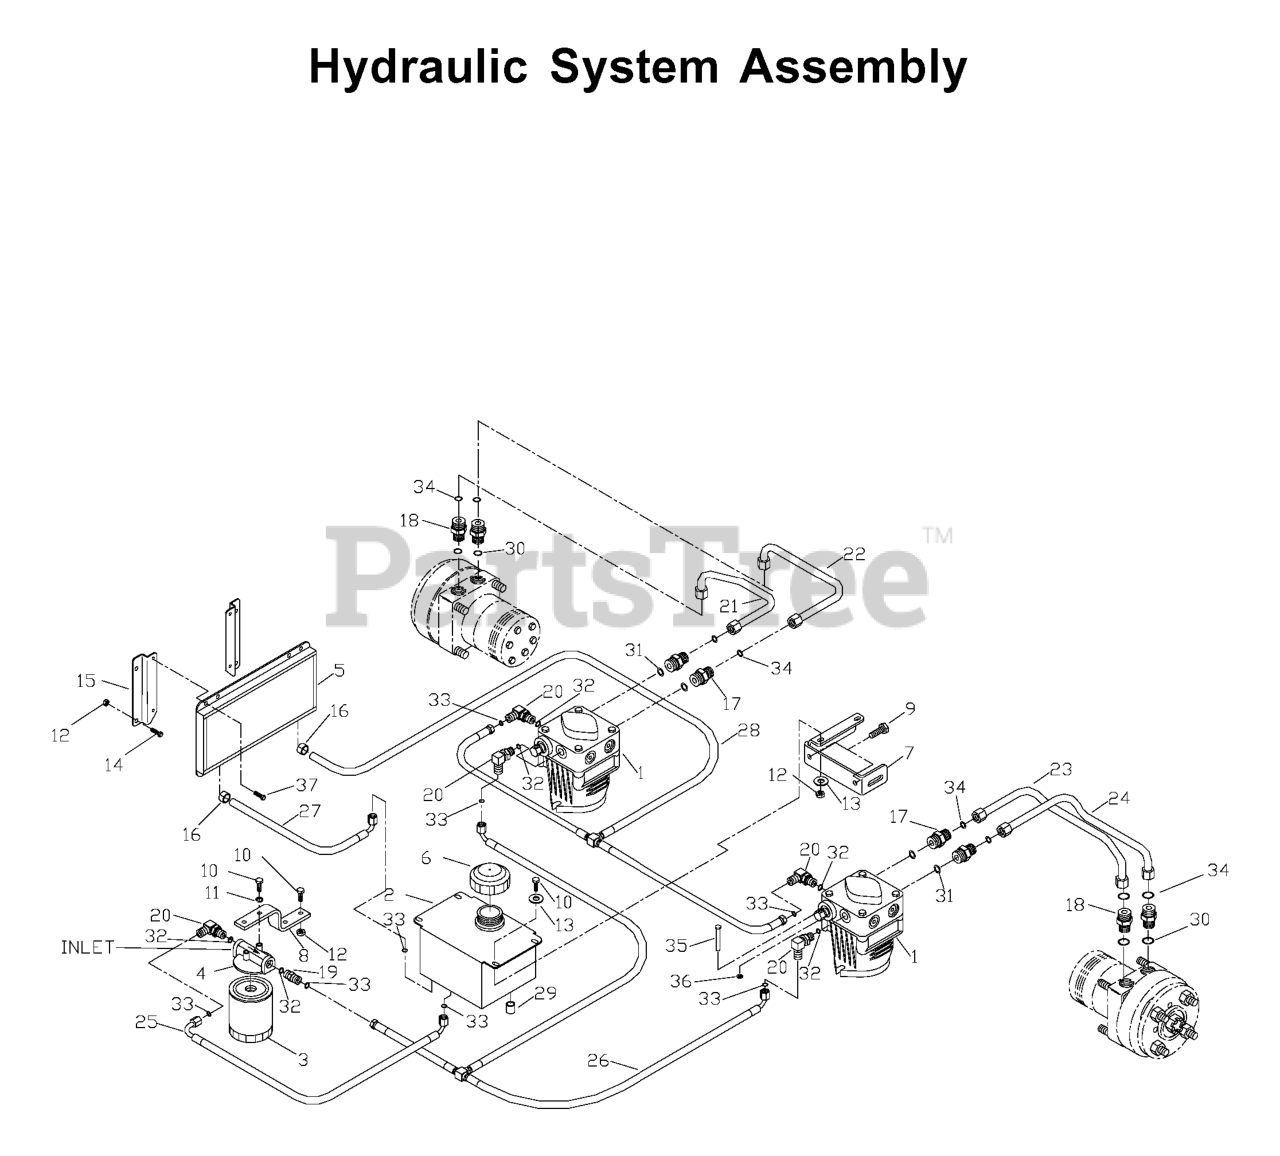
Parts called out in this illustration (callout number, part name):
1	PUMP
3	HYDRAULIC OIL FILTER
4	FILTER HEAD
6	HYDRAULIC CAP
7	TANK MOUNT LT
8	FILTER MOUNT
9	HCS 5/16C X 3/4
10	HCS 1/4C X 3/4 HCS
11	LOCKWASHER 1/4"
12	NUT 1/4C CENTERLOCK
13	WASHER 1/4 FLAT
14	HCS 1/4C X 2
15	FRONT COOLER BRKT
16	HOSE CLAMP T-1865
17	FITTING, STRAIGHT F6400-8-8-0
19	STRAIGHT FITG
20	ELBOW, F6801-6-6-0 90 DEGREE
21	RUBBER HYDRAULIC HOSE (1)
22	RUBBER HYDRAULIC HOSE (1)
23	RUBBER HYDRAULIC HOSE (1)
24	RUBBER HYDRAULIC HOSE (1)
29	NUT 9/16-18 JIC CAP
37	HEX CAP SCREW 1/4
539105026	TANK MOUNT RT
539105767	COOLER BRACKET
